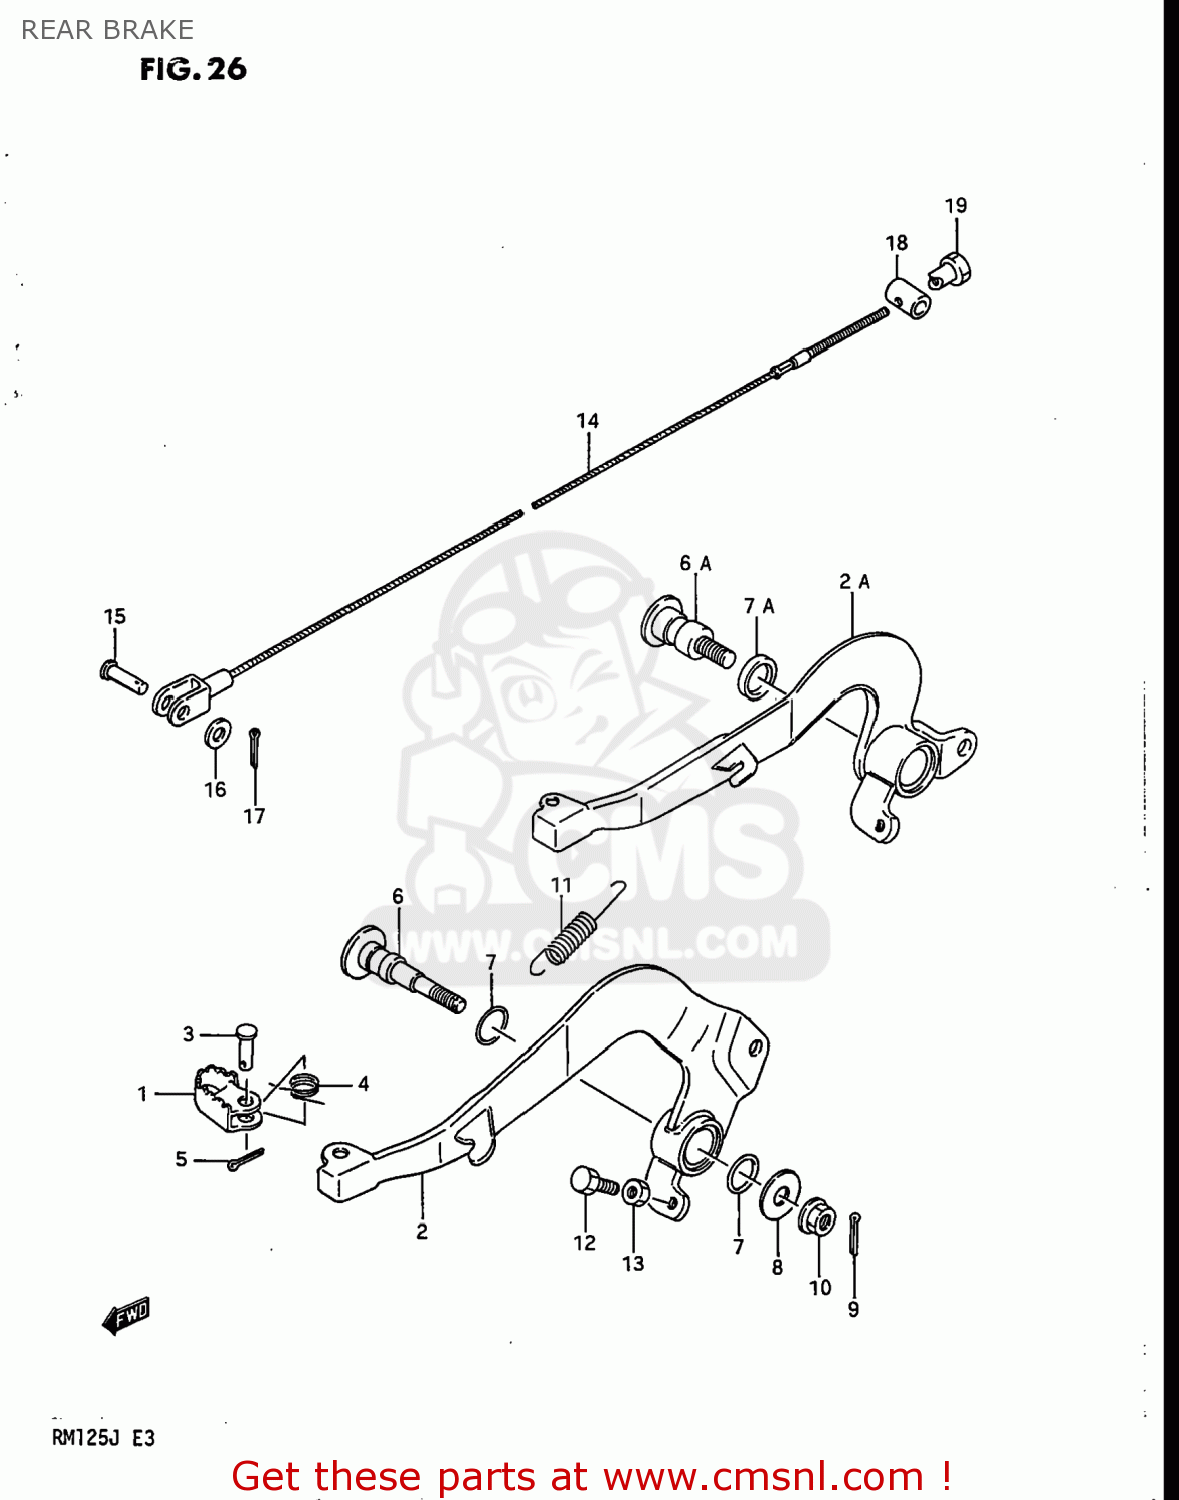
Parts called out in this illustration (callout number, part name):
1	PEDAL,BRAKE
2	ARM,BRAKE PEDAL
2A	ARM COMP,BRAKE PEDAL
3	PIN
4	SPRING
5	PIN
6	SHAFT,BRAKE PEDAL
6A	SHAFT,BRAKE PEDAL
7	O-RING,BOSS
7A	SEAL,OIL(15X20X3)
8	WASHER
9	PIN 20X20
10	NUT
11	SPRING BRAKE PEDAL
12	BOLT
13	NUT
14	CABLE,RR BRAKE
15	PIN(L:17.5)
16	WASHER
17	PIN 20X20
18	PIN
19	NUT (6MM)
